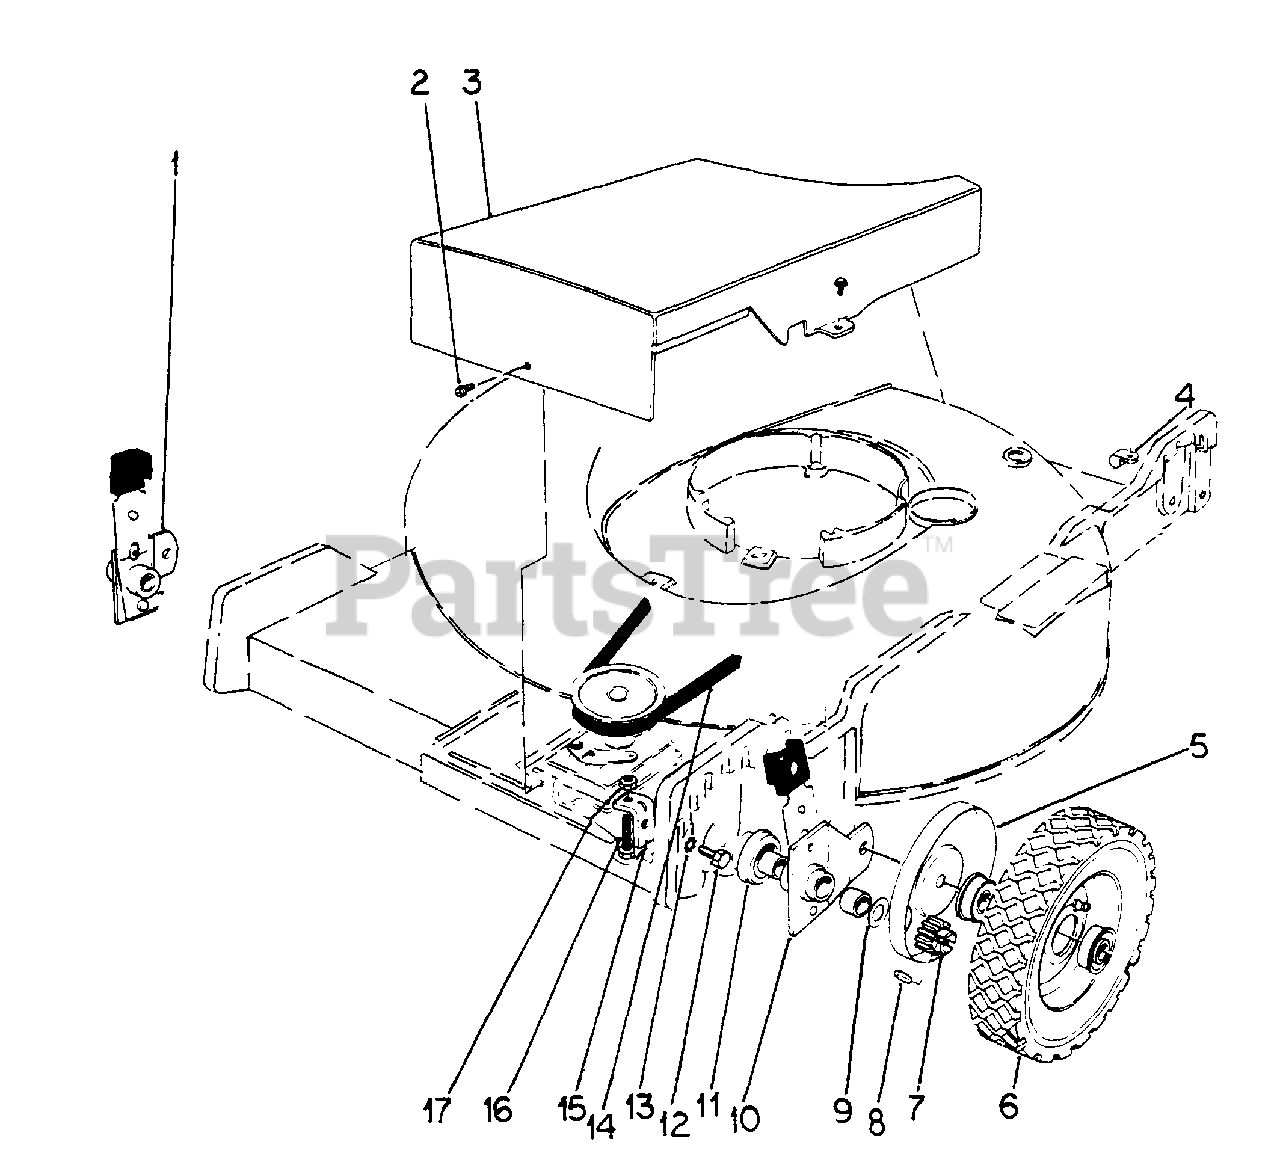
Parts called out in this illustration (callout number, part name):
1	ARM, PIVOT RH
3	COVER, BELT DRIVE
4	CLAMP, CABLE
5	COVER, WHEEL
6	WHEEL & TIRE ASSY, FRONT
7	GEAR, PINION
8	PIN, 1/8 X 3/4 HVY COILED SPRING
9	WASHER, THRUST
10	ARM, PIVOT LH
12	BOLT, 5/16-18 X 1 ZND HEX-HD
13	WASHER, 5/16 INT TOOTH LOCK
14	BELT, DRIVE
15	BRACKET, ADJUSTING
17	NUT, 1/4-2C LOCK
